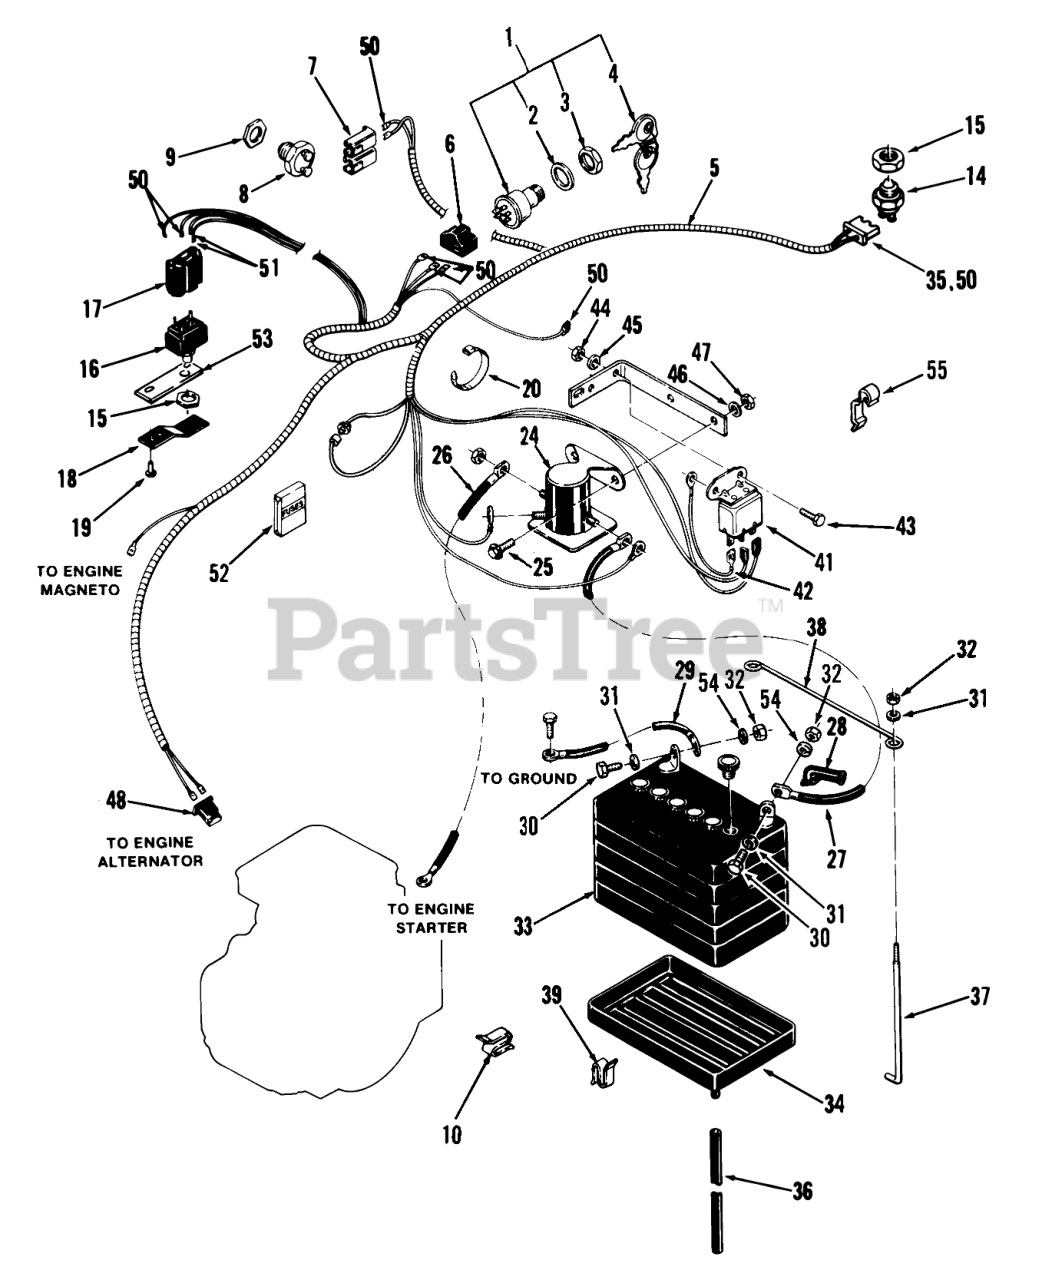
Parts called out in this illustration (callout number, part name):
1	SWITCH-IGNITION
2	LOCKWASHER
4	Key-EL
5	Wiring Harness
6	CONNECTOR-5 WAY-SERV
7	CONNECTOR BODY
8	SWITCH-INTERLOK CLUT
9	NUT-SPECIAL 9/16-18
10	SPEED CLIP
14	SWITCH-INTERLOK CLUT
15	NUT-SPECIAL 9/16-18
16	SWITCH-CLUTCH
17	CONNECTOR 5 WAY
18	CLIP-SWITCH
19	RIVET
20	PLASTIC TIE
24	SOLENOID
25	Screw
26	Wire
27	Cable
28	Boot
29	WIRE-GROUND
30	Bolt
32	Nut
33	Battery
34	TRAY-BATTERY
35	CONNECTOR BODY
36	TUBE-BATTERY DRAIN
38	ROD-HOLD DOWN
39	CLIP
41	Relay
42	RELAY-GROUND WIRE
43	Bolt 10-32 X 5/8
44	Nut
45	Lockwasher Internal
46	LOCKWASHER
47	Nut
48	Conn Body Part of 7
50	Terminal
51	TERMINAL-TAB RCPT
53	CLAMP-PTO SWITCH
54	Washer
55	CLIP-WIRE
